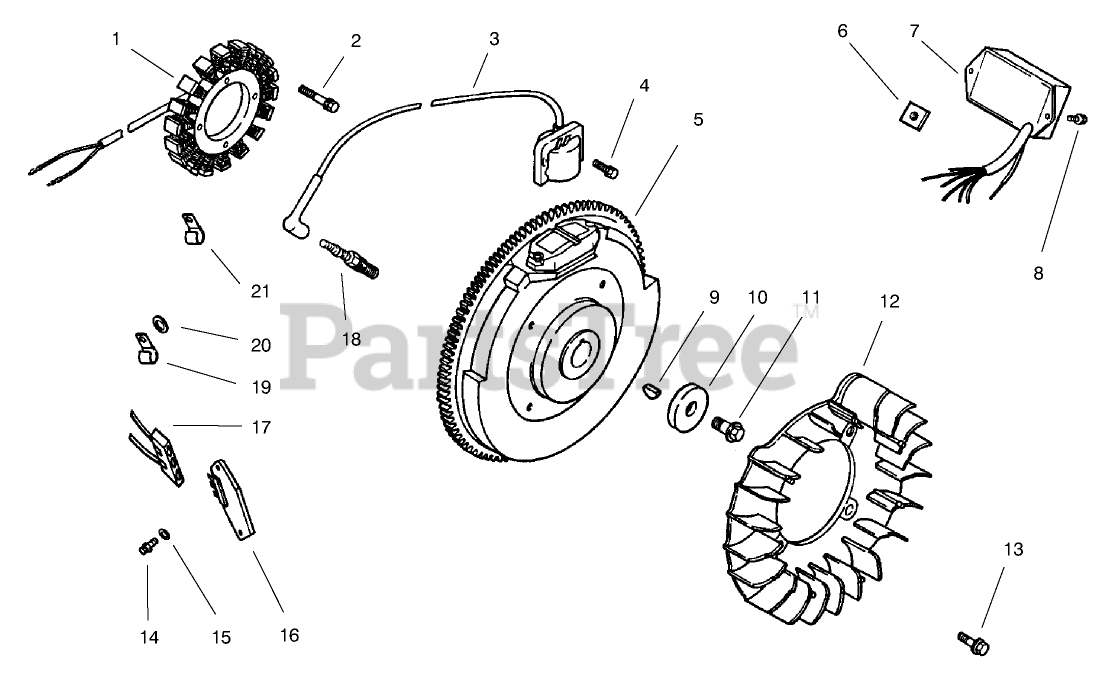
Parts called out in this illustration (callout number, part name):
1	Kit, 15 amp stator (Incl. 24 126 71 bracket)
2	Screw
3	Module-Ignition
4	Screw-HSH
5	Flywheel
6	Nut-Plastic
7	Module, speed adv.
8	Screw
9	Key
10	Washer
11	Screw
12	Fan
13	Bolt-Shoulder
14	Screw
15	Washer
16	Rectifier-Regulator
17	Connector
18	Plug-Spark
19	Clamp
20	Washer
21	Clip
